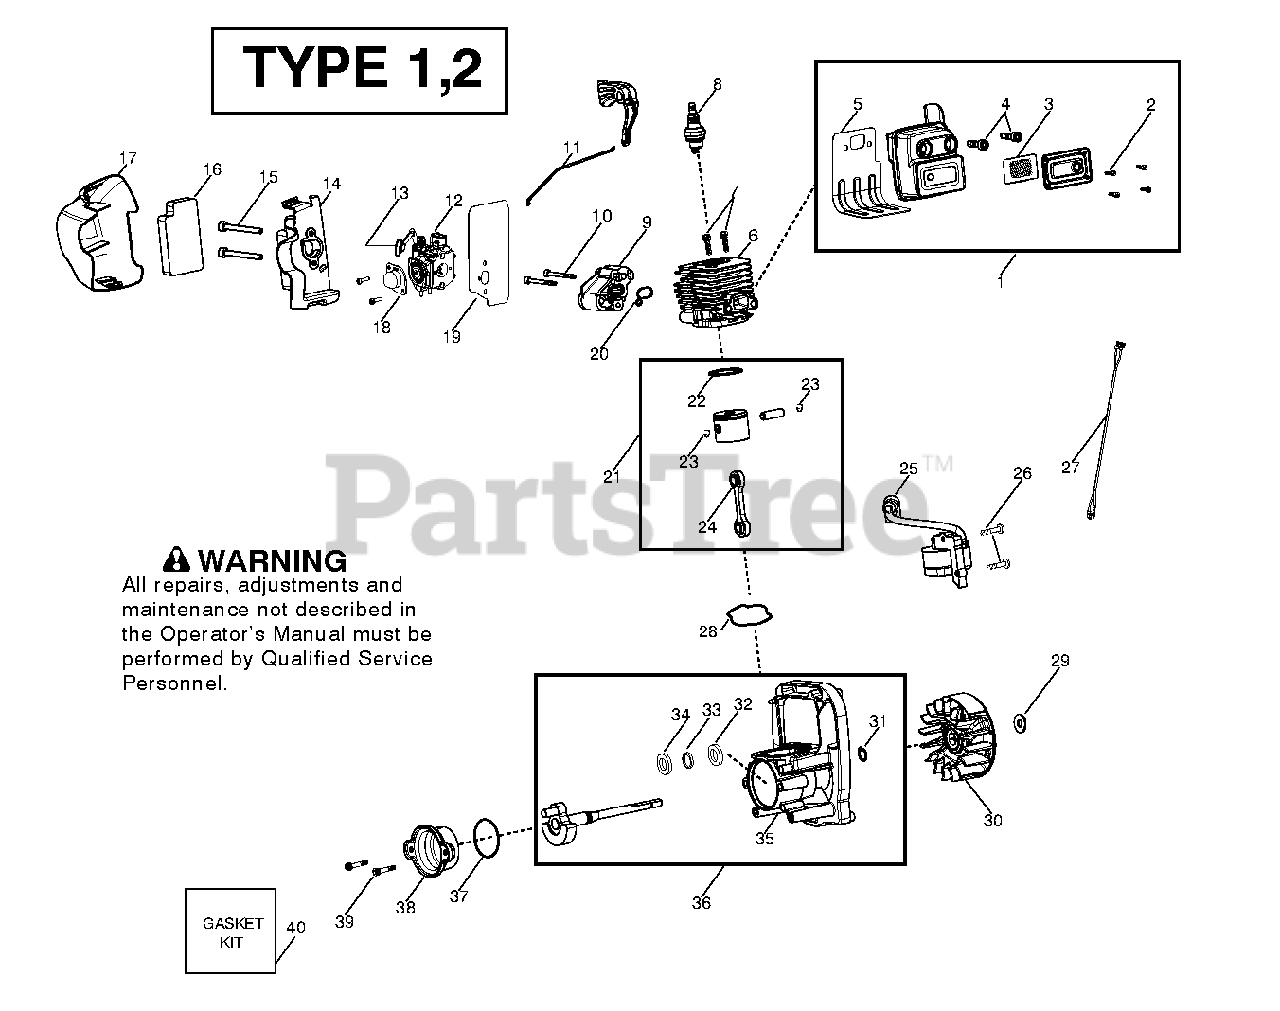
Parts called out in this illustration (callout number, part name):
1	ASSY MUFFLER WELDED
2	SCREW-6-19X5/16PLAST PA
3	Muffler Assembly, Welded
5	KIT GASKET 25CC
6	CYLINDER CHROME 25CC
8	PLUG-SPARK (RCJ-6Y)
9	ADAPTER CARBURETOR
11	LINKAGE THROTTLE
12	KIT CARBURETOR WT-875A
13	LEVER CHOKE WT-875
14	BASE AIRBOX RED
16	AIR FILTER FOAM
17	COVER AIRBOX BLACK
18	PURGE BULB 188-16
19	KIT GASKET 25CC
20	KIT GASKET 25CC
21	KIT PISTON CONN ROD
22	RING-PISTON
23	WRIST PIN RET.
24	KIT PISTON CONN ROD FORGED
25	KIT MODULE W/0 INTERRUPT
28	KIT GASKET 25CC
30	ASSY FLYWHEEL
31	RETAINING RING
32	OUTER BEARING
34	BEARING
35	ASSY CRANKCASE
36	ASSY CRANKCASE & CRANKSHAFT
37	KIT GASKET 25CC
38	ASSY REAR PLUG
40	KIT GASKET 25CC
